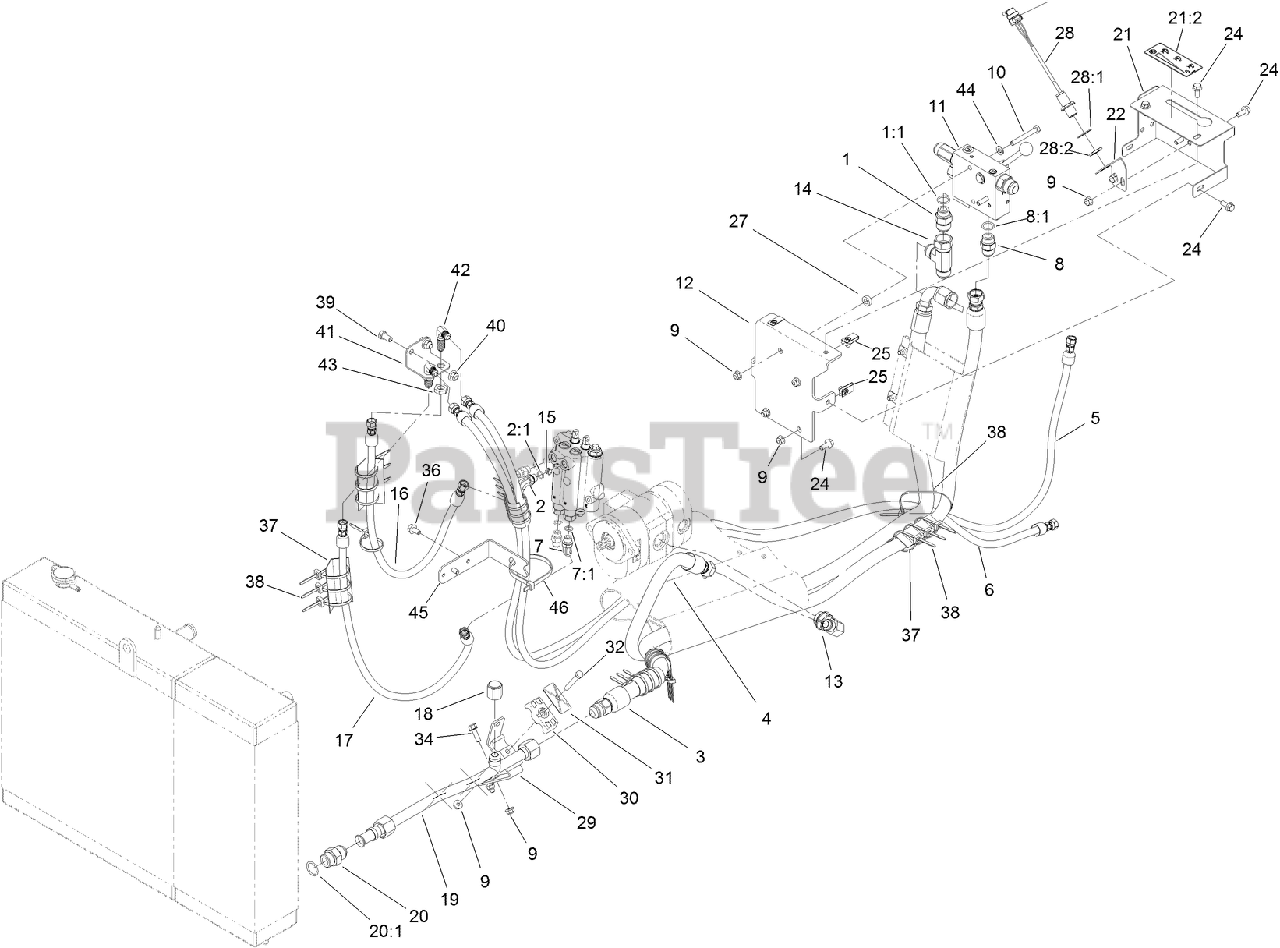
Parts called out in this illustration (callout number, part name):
1	FITTING-STRAIGHT
1:1	O-RING
2	FITTING-ELBOW, 90 DEG
2:1	O-RING
3	HOSE ASM
4	HOSE ASM
5	HOSE ASM
6	HOSE ASM
7	FITTING-ELBOW, 45 DEG
7:1	O-RING
8	FITTING-STRAIGHT
8:1	O-RING
9	NUT-HF, NI
10	SCREW-HH
11	VALVE-CONTROL, VIBE PLOW
12	PLATE-VALVE, PLOW
13	ADAPTOR-ELBOW
14	FITTING-TEE
15	ORIFICE
16	HOSE ASM
17	HOSE ASM
18	FITTING-CAP
19	HYD TUBE ASM
20	FITTING-STRAIGHT
20:1	O-RING
21	COVER PLATE ASM
21:2	DECAL-VIBE PLOW CONTROL
22	PLATE-SENSOR
24	SCREW-HHF
25	NUT-U TYPE
27	SPACER
28	PROXIMITY SWITCH ASM
28:1	NUT-HEX
28:2	WASHER-LOCK, INTERNAL TOOTH
29	BRACKET-TUBE
30	CLAMP-TUBE
31	PLATE-COVER
32	SCREW-HH
34	SCREW-HHF
36	SCREW-HHF
37	PROTECTOR-HOSE
38	TIE-CABLE
39	SCREW-HH
40	NUT-HF, NI
41	PLATE-BULKHEAD
42	UNION-BULKHEAD, ELBOW 90
43	NUT-LOCK, BULKHEAD
44	WASHER-PLAIN
45	BRACKET-HOSE
46	TIE-CABLE
